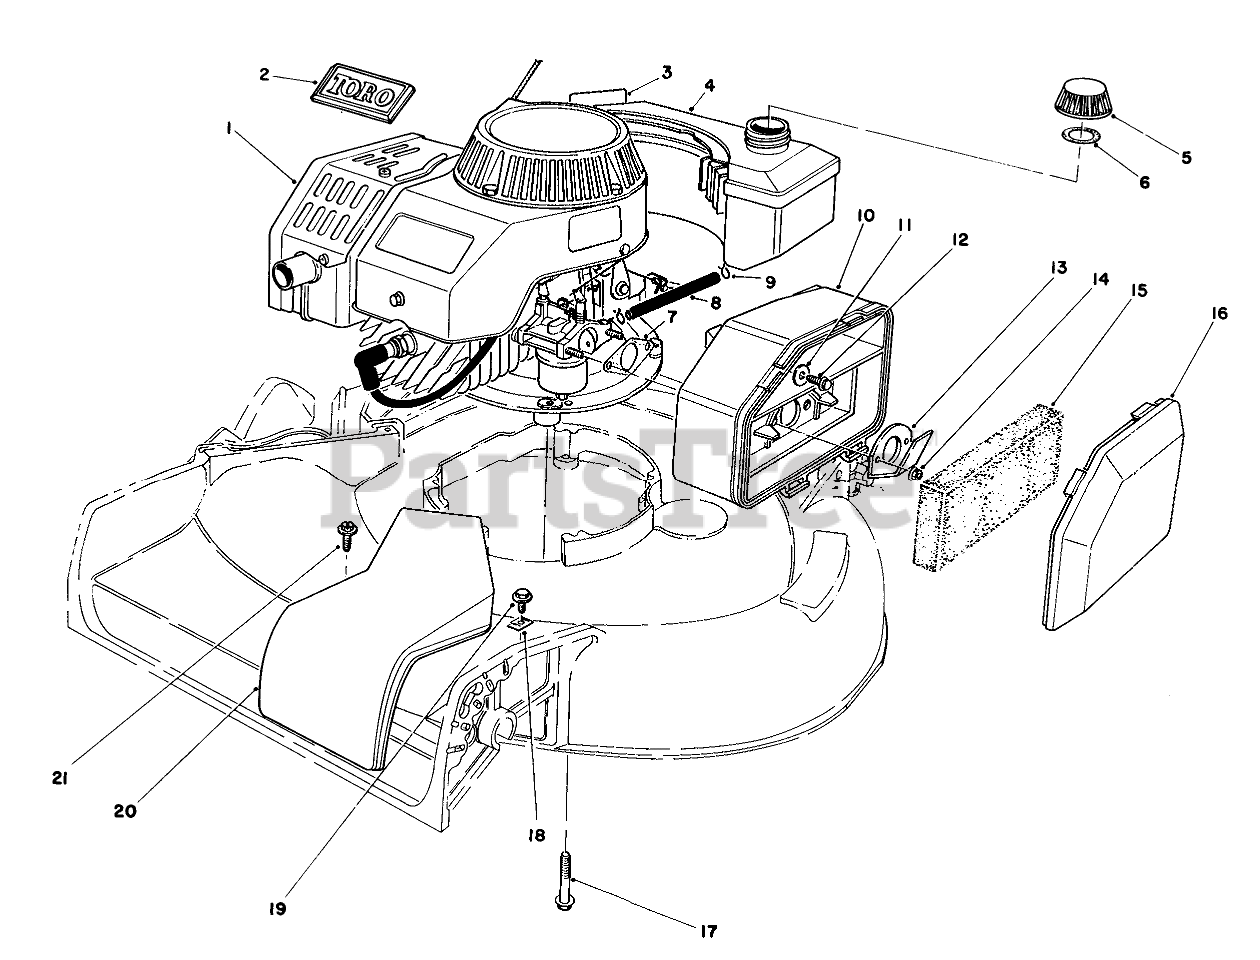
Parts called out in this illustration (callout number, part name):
1	Engine
2	TORO LOGO PLT
3	Decal-Maintenance
4	Fuel Tank Assembly
5	Gas Cap Assembly (Incl.Ref. #5)
6	GAS CAP GASKET
7	GASKET-AIR CLEANER
8	FUEL LINE
9	CLAMP-HOSE
10	AIR CLEANER
11	WASHER-FLAT
12	SCREW-HH
13	SPIT BACK DEFLECTOR
14	NUT-LOCK
15	FILTER
16	AIR CLEANER COVER
17	FLG SCREW,3/8-16X2.000
18	Cable Clamp
19	SCREW-HWHTF
20	Cow-Belt
21	SCREW
